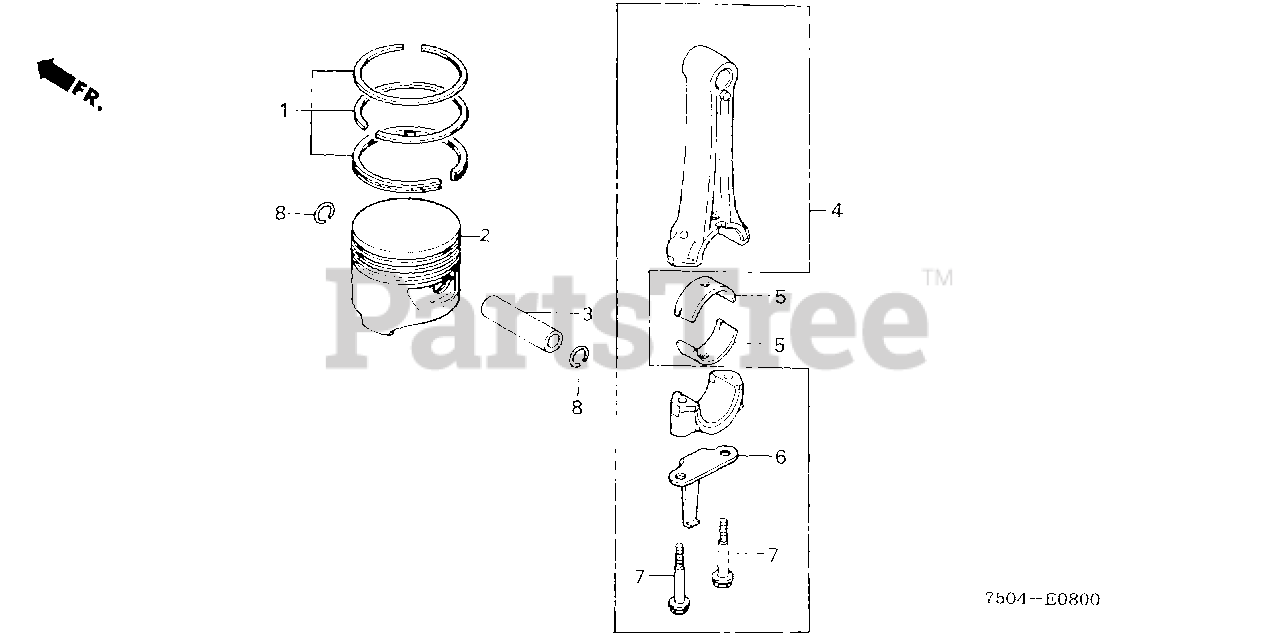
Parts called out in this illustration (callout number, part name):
1	RING SET, PISTON (STD)
1	RING SET, PISTON (STD) (NOT AVAILABLE)
1	RING SET, PISTON (OS 0.25)
1	RING, PISTON (OS 0.50)
1	RING SET, PISTON (OS 0.50)
1	RING SET, PISTON (0.75)
2	PISTON (STD)
2	PISTON (OS 0.25)
2	PISTON (OS 0.50)
2	PISTON (0.75)
3	PIN, PISTON
4	ROD ASSY., CONNECTING
5	BEARING A, CONNECTING ROD (BLACK)
5	BEARING B, CONNECTING ROD (BROWN)
5	BEARING C, CONNECTING ROD (GREEN)
5	BEARING D, CONNECTING ROD (YELLOW)
5	BEARING E, CONNECTING ROD (PINK)
5	BEARING A, CONNECTING ROD
5	BEARING B, CONNECTING ROD
5	BEARING C, CONNECTING ROD
6	DIPPER, CONNECTING ROD
7	BOLT, CONNECTING ROD (8MM)
8	CLIP, PISTON PIN (19MM)
